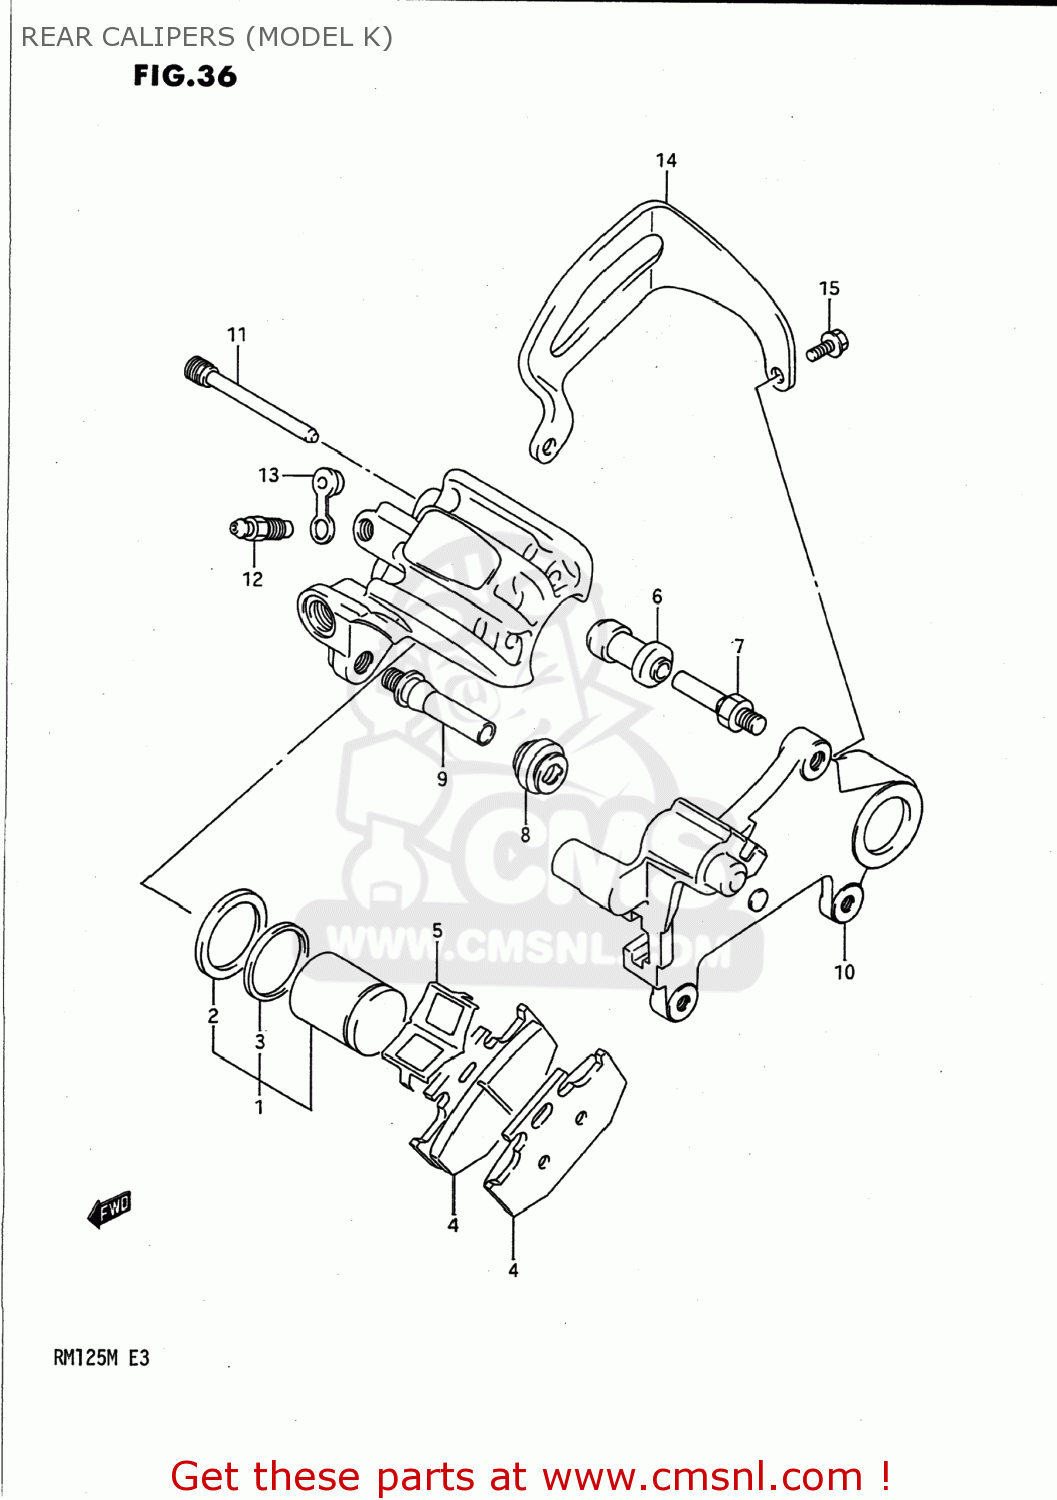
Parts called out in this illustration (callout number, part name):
1	PISTON SET
2	SEAL,PISTON
3	SEAL,DUST
4	PAD
5	SPRING
6	BOOT
7	PIN,BOLT
8	BOOT
9	PIN
10	BRACKET
11	PIN,HANGER
12	BLEEDER
13	CAP,BLEEDER
14	GUARD,REAR CALIPER
15	BOLT
